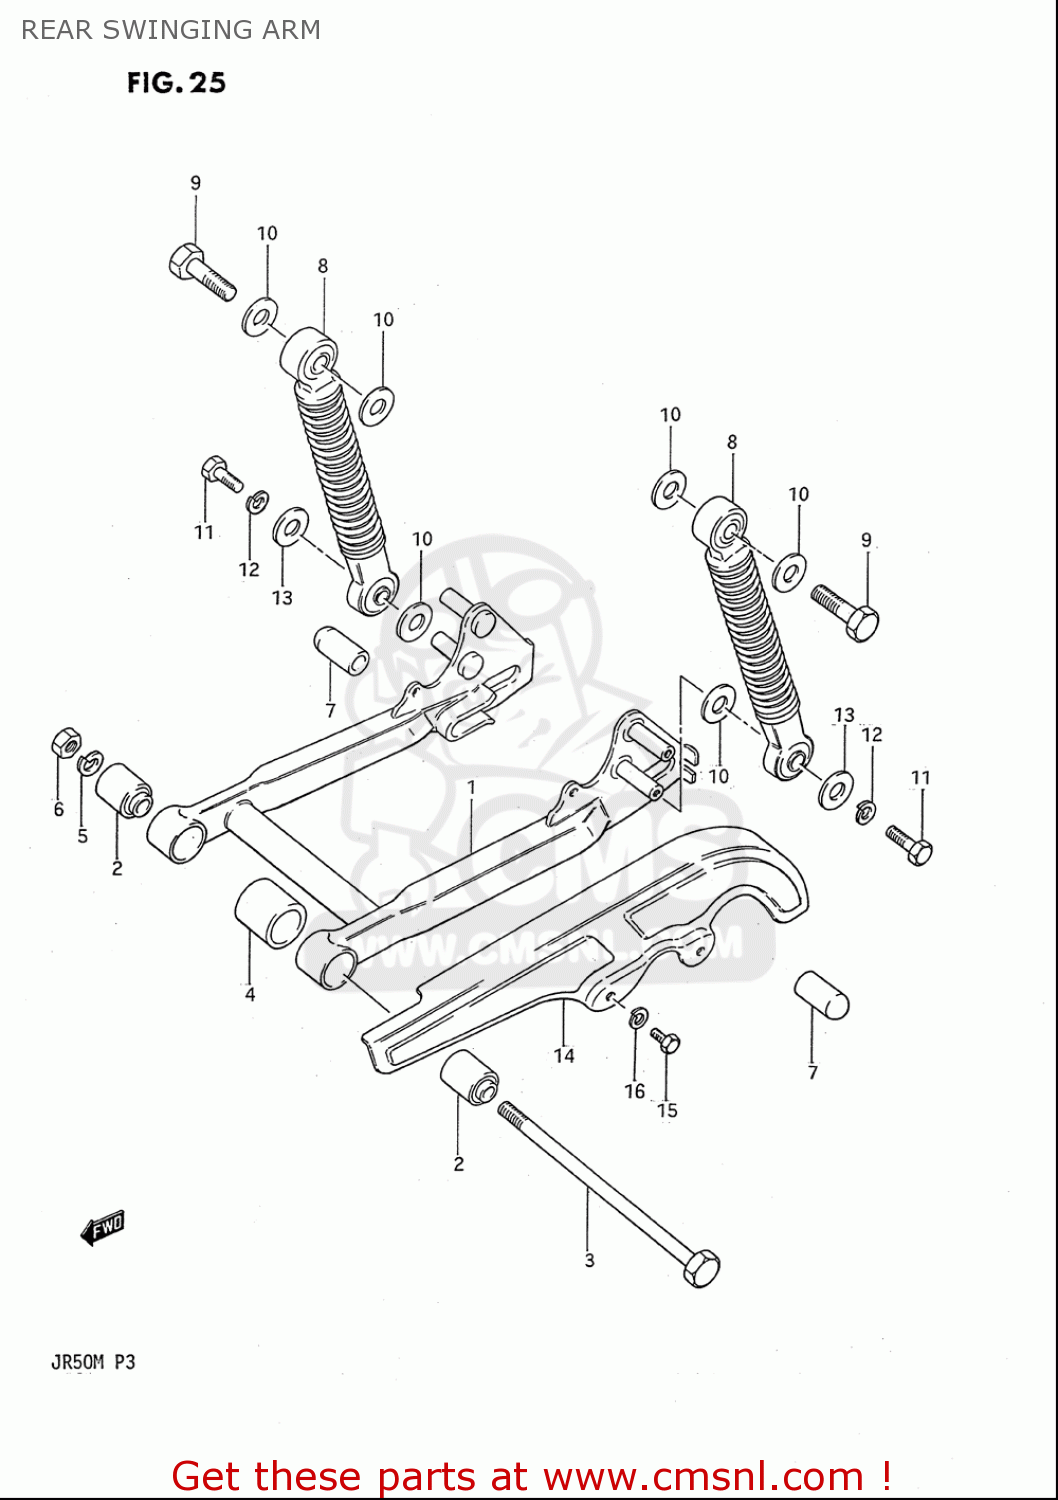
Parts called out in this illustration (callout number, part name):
1	ARM,REAR SWING
2	BUSH
3	SHAFT,RR SWINGINGARM PIVOT
4	CUSHION
5	WASHER,LOCK
6	NUT
7	CAP,RR SHOCK ABSORBER BOSS
8	ABSORBER ASSY,RR SHOCK
9	BOLT
10	WASHER
11	BOLT
12	WASHER,LOCK
13	WASHER(6.5X24X1.6)
14	CASE,CHAIN
15	BOLT
16	WASHER,LOCK
